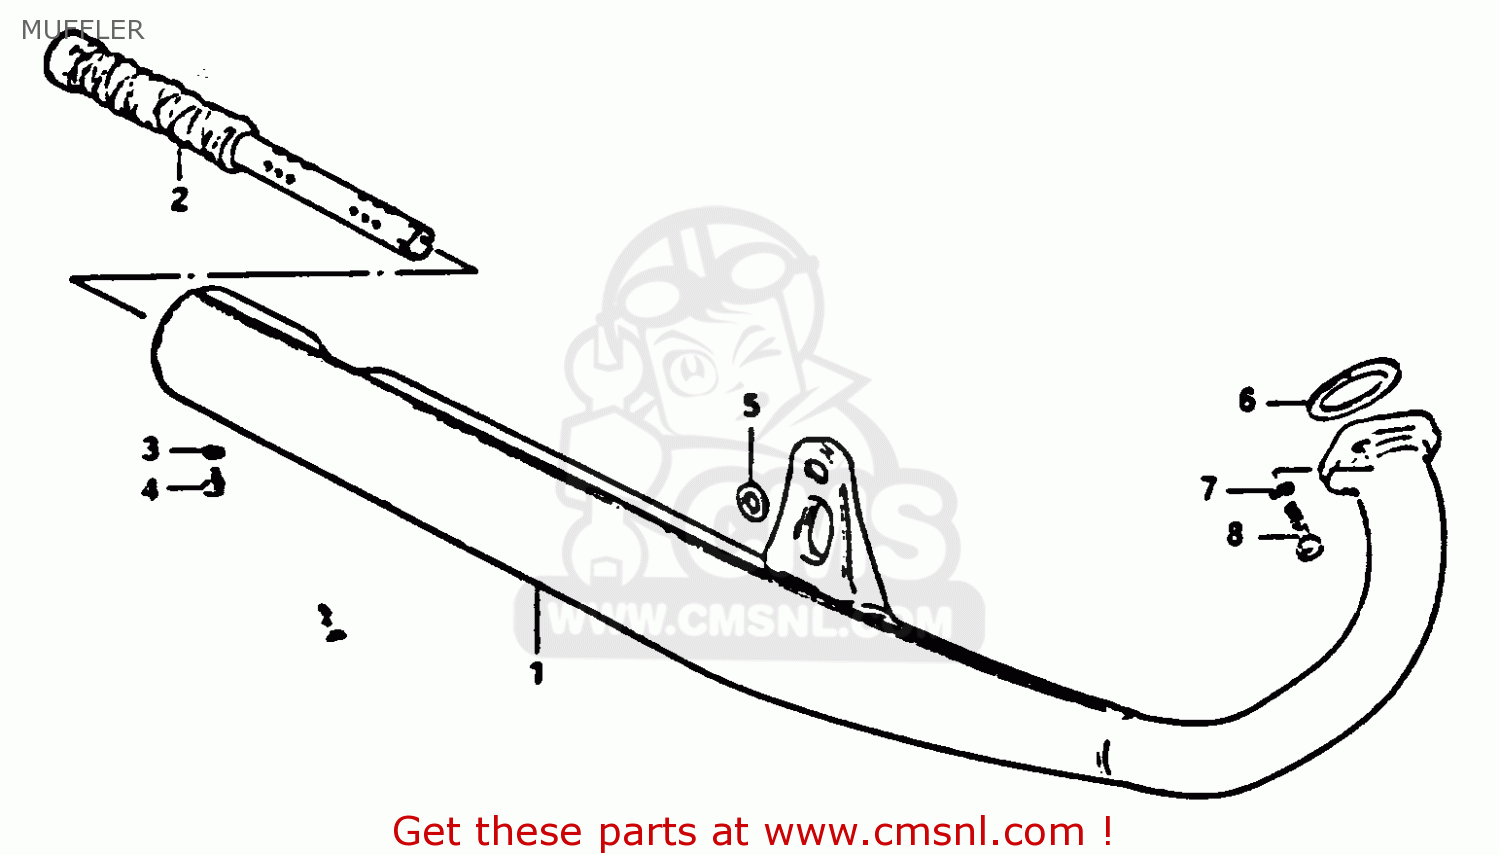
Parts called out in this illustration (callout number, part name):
1	MUFFLER ASSY
2	PIPE, BAFFLE
3	LOCK WASHER
4	BOLT(5X8)
5	WASHER (12.5X24X3.2)
6	GASKET,EXHAUST PIPE (NAS)
7	LOCK WASHER
8	BOLT
